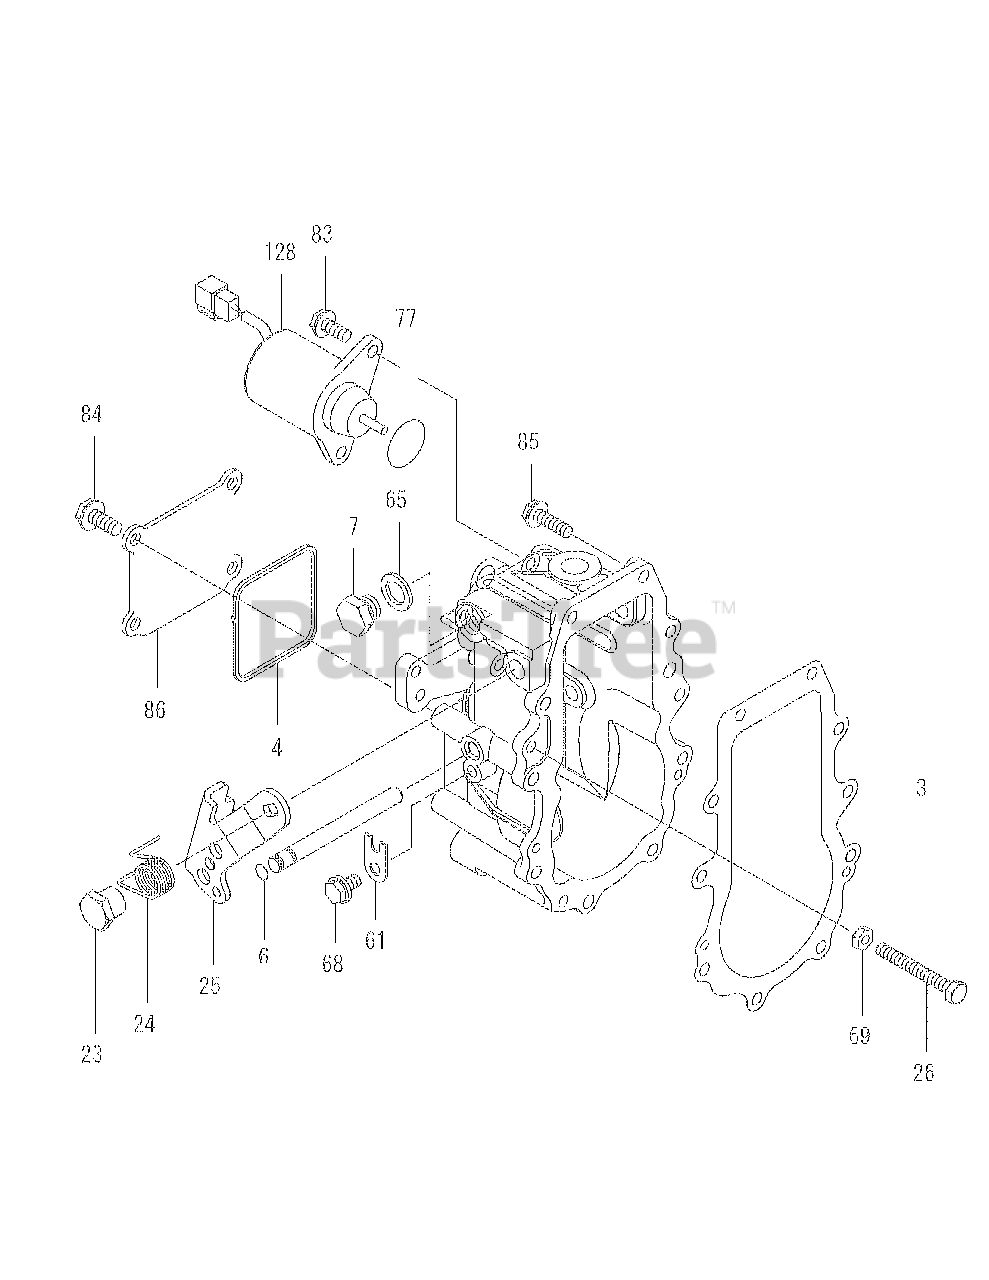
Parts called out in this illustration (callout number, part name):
25	Regulator Lever
61	Shaft Retainer
65	Seal Washer, 12
86	Governor Case Cover
